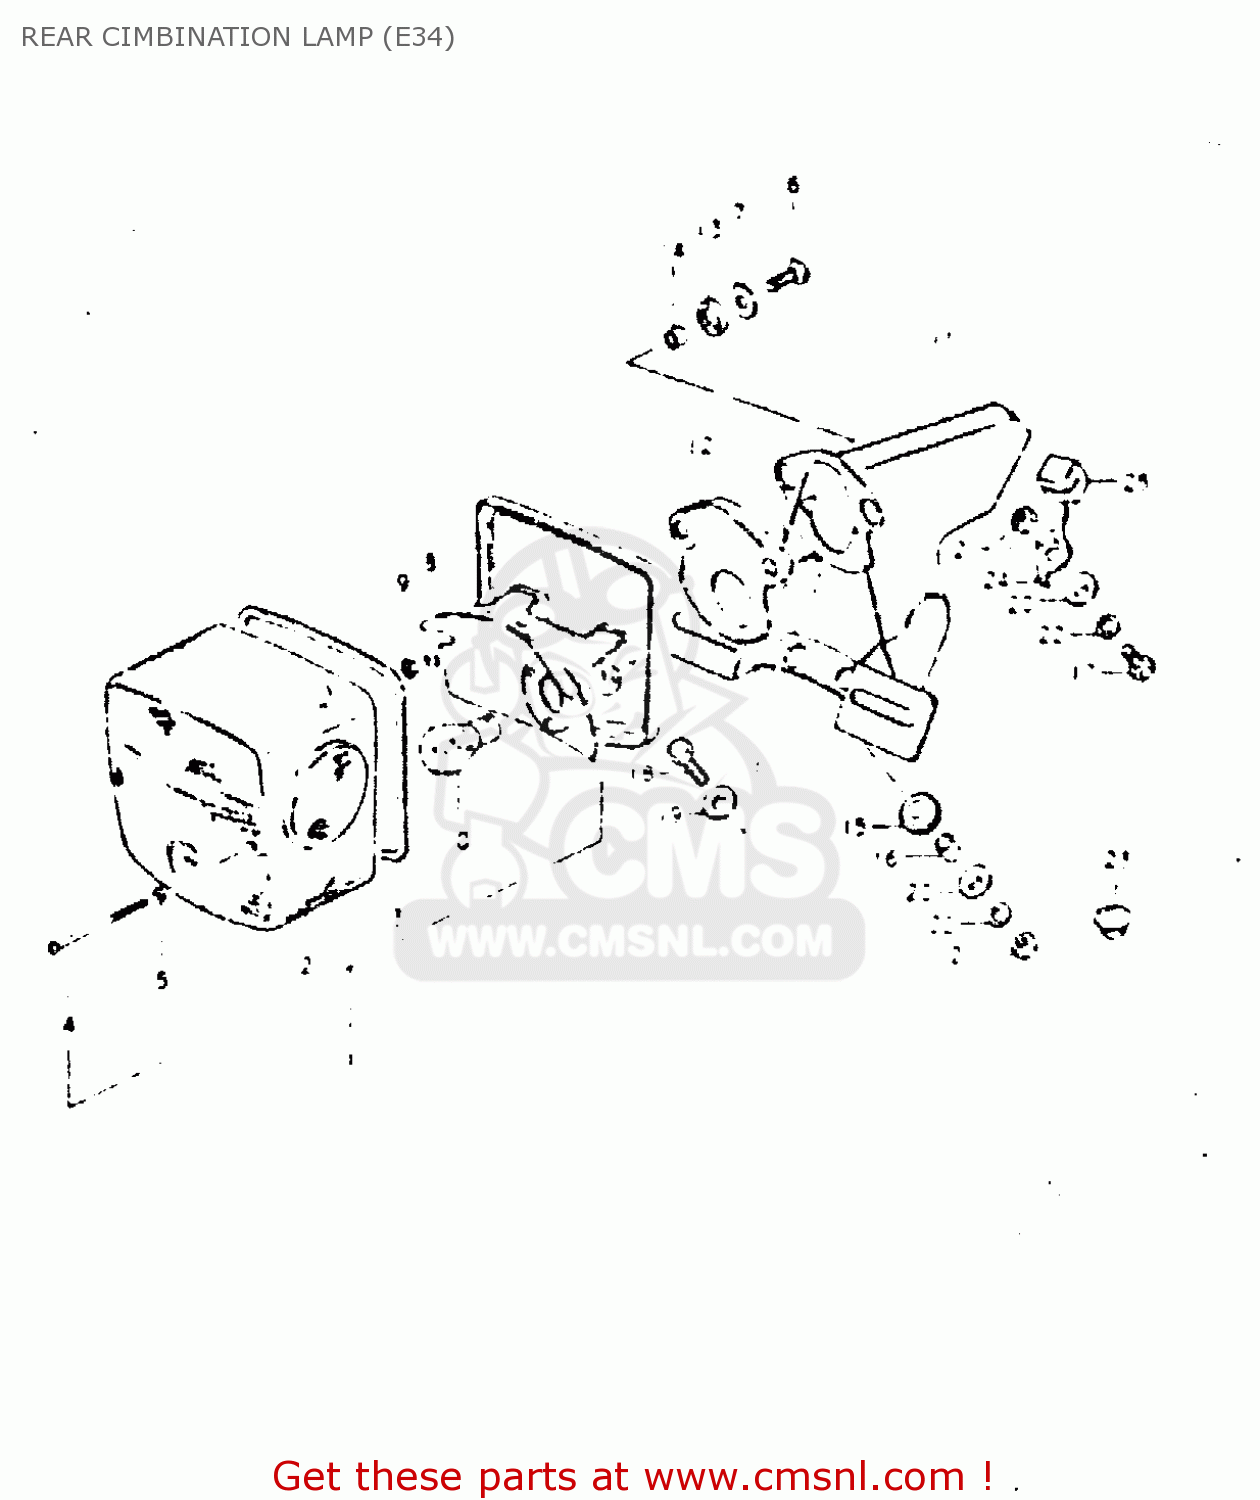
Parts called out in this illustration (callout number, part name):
1	LAMP UNIT, TAIL
2	LENS
3	GASKET (NAS)
4	SCREW (4X55)
5	GASKET (NAS)
6	SCREW
7	WASHER,REAR COMBINATION LAMP
8	NUT
9	LOCK WASHER
10	BULB (6V,21/5W)
11	BRACKET SET
12	CUSHION
13	CUSHION
14	SPACER,REAR COMBINATION LAMP
15	CUSHION,REAR COMBINATION LAMP
16	SPACER
17	BOLT
18	BOLT
19	WASHER (6.5X20X1.2)
20	WASHER
21	NUT
22	WASHER
23	GROMMET
24	PLATE,TAIL LAMP
25	CUSHION,REAR COMBINATION LAMP
